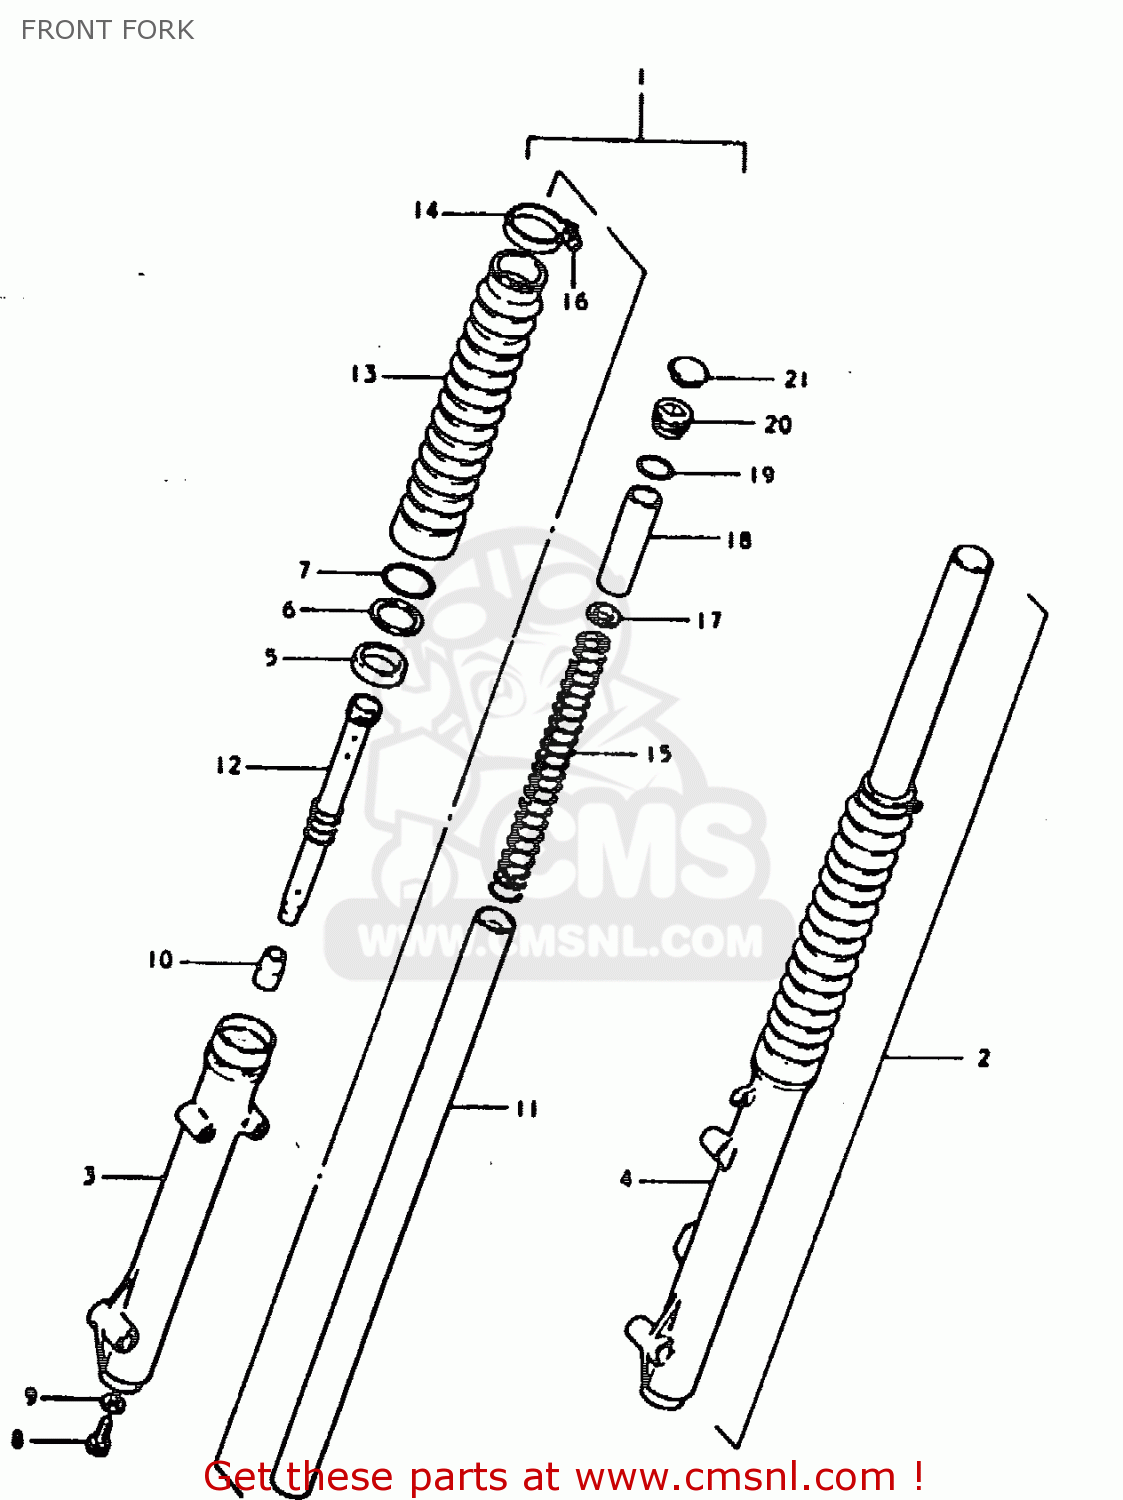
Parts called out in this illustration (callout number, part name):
1	DAMPER ASSY, RH
2	DAMPER ASSY, LH
3	TUBE,FORK,OUTER,RIGHT
4	TUBE,OUTER,LEFT
5	OIL SEAL,FRONT FORK
6	WASHER
7	RING,SNAP
8	BOLT,FORK CYLINDER(10X25)
9	GASKET (NAS)
10	PIECE,OIL LOCK
11	TUBE,FORK,INNER
12	CYLINDER
13	BOOT
14	BAND,FORK COVER BOOT
15	SPRING
16	SCREW
17	GUIDE,SPRING COVER
18	SPACER,SPRING
19	O-RING,FORK INNER TUBE
20	CAP
21	CAP,FRONT FORK
